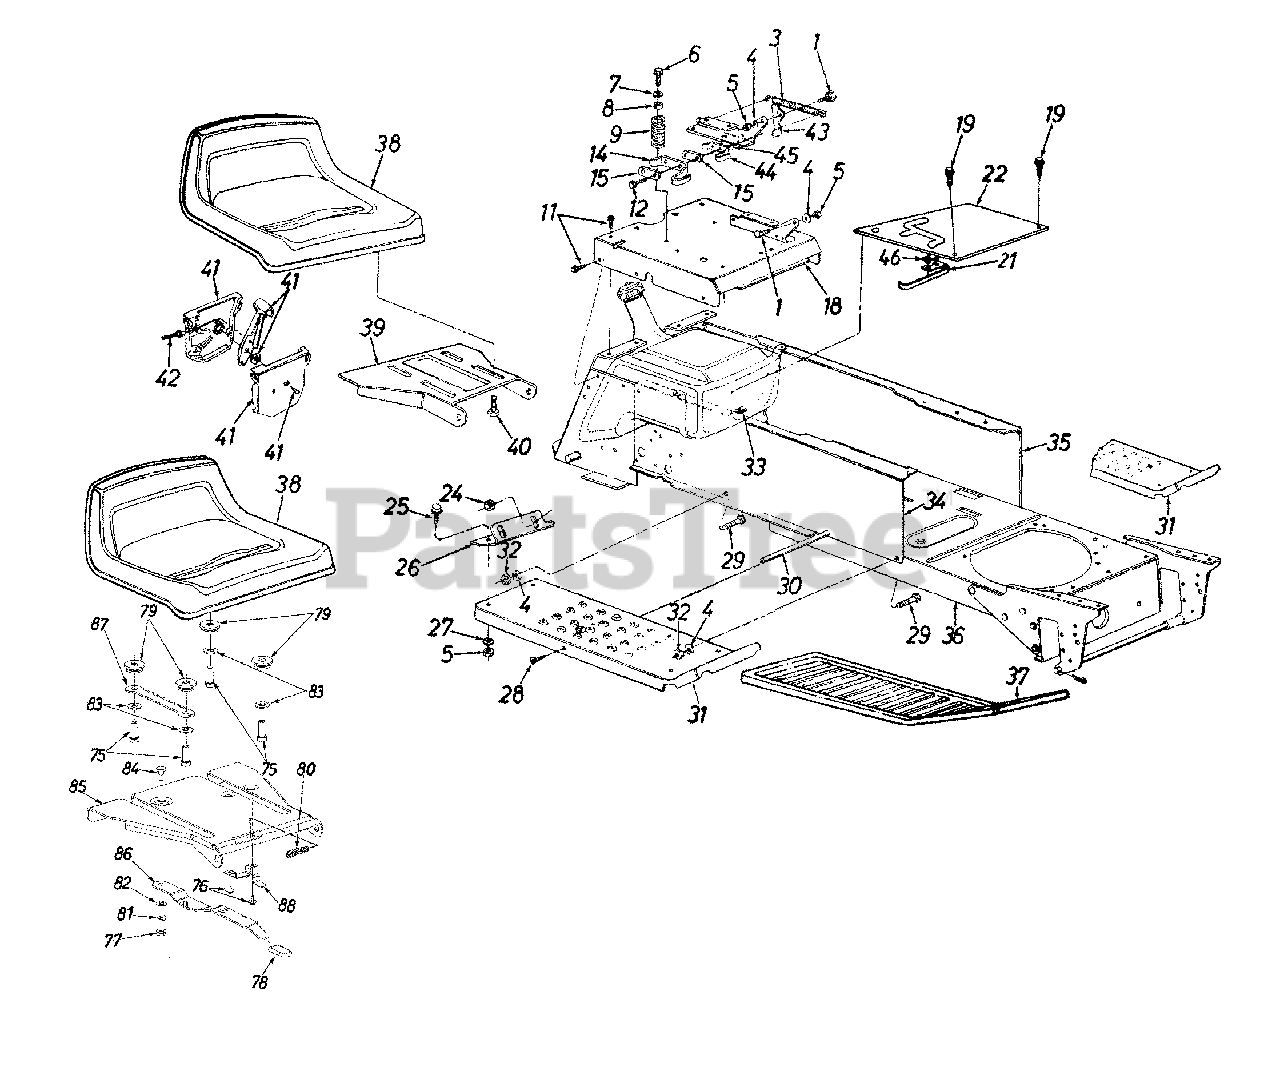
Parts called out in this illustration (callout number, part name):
1	Shld. Bolt .437" Dia. x .162"
3	Ext. Spring 5.31" Lg.
4	L-Wash. 5/16" I.D.
5	Hex Nut 5/16-18 Thd. (Gr. 5)
6	Hex Wash. Hd. Tap Scr. 5/16 -18 x .7" Lg.
7	Fl-Wash. .344" I.D.
8	Bushing
9	Compression Spring
11	Hex Wash. Hd. AB-Tap Scr. 5/16 x .75" Lg.
14	Spring Switch
15	Insulator Plate
18	Seat Plate
19	Truss Mach. B-Tap Scr.
21	Reverse Safety Switch
25	Hex Bolt 5/16-18 x .75" Lg.
28	Truss Mach. Scr. 5/16-18 x .75" Lg.
29	Rib Neck Bolt 5/16-24 x .75" Lg.
30	Running Board Rod
33	Speed Nut #10Z
38	Seat 8-7/8" High
40	Hex Tap Scr. 3/8-16 x .62" Lg.
41	Throttle Control Box Ass'y.
42	Throttle Control Wire 35" Lg.
43	Seat Lift Bracket
44	Seat Spring Switch
45	Insulator Boss Plate
46	Insulator Nut Plate
75	Hex Bolt 3/8-16 x 1" Lg.
76	Hex Wash. Hd. B-Tap Scr. #10-16 x .38" Lg.
77	Hex Flanged L-Nut 1/4-20 Thd.
78	Seat Adjustable Grip
79	Spacer
80	Compression Spring 1.5" Lg.
81	Spring Wash. .265" I.D. x .56" O.D.
82	Fl-Wash. .344" I.D. x .62" O.D.
83	Fl-Wash. .406" I.D. x .875" O.D.
84	Shld. Bolt .34" x 1/4 -20 Thd.
87	Seat Selector
88	Seat Stop
